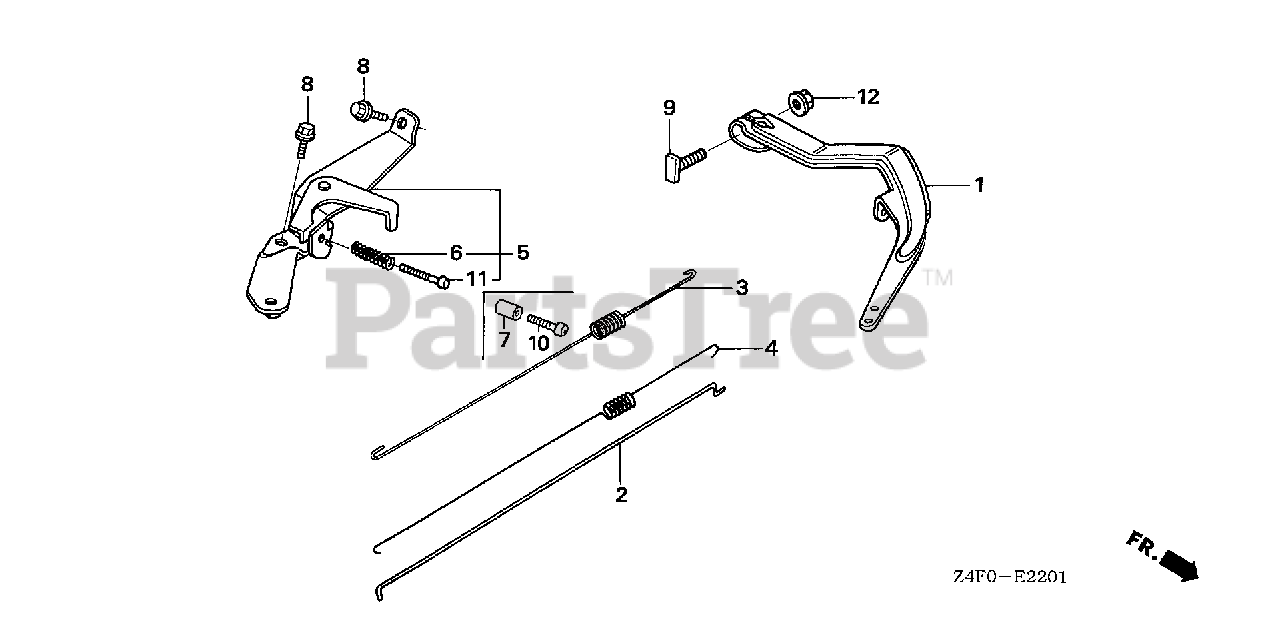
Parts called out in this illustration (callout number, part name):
1	ARM, GOVERNOR
2	ROD, GOVERNOR
3	SPRING, GOVERNOR
4	SPRING, THROTTLE RETURN
5	CONTROL ASSY.
6	SPRING, CONTROL ADJUSTING
7	COLLAR, STOPPER
8	BOLT, FLANGE (6X12) (CT200)
9	BOLT, GOVERNOR ARM
10	SCREW, RECESSED (5X25)
11	SCREW, PAN (5X35)
12	NUT, FLANGE (6MM)
